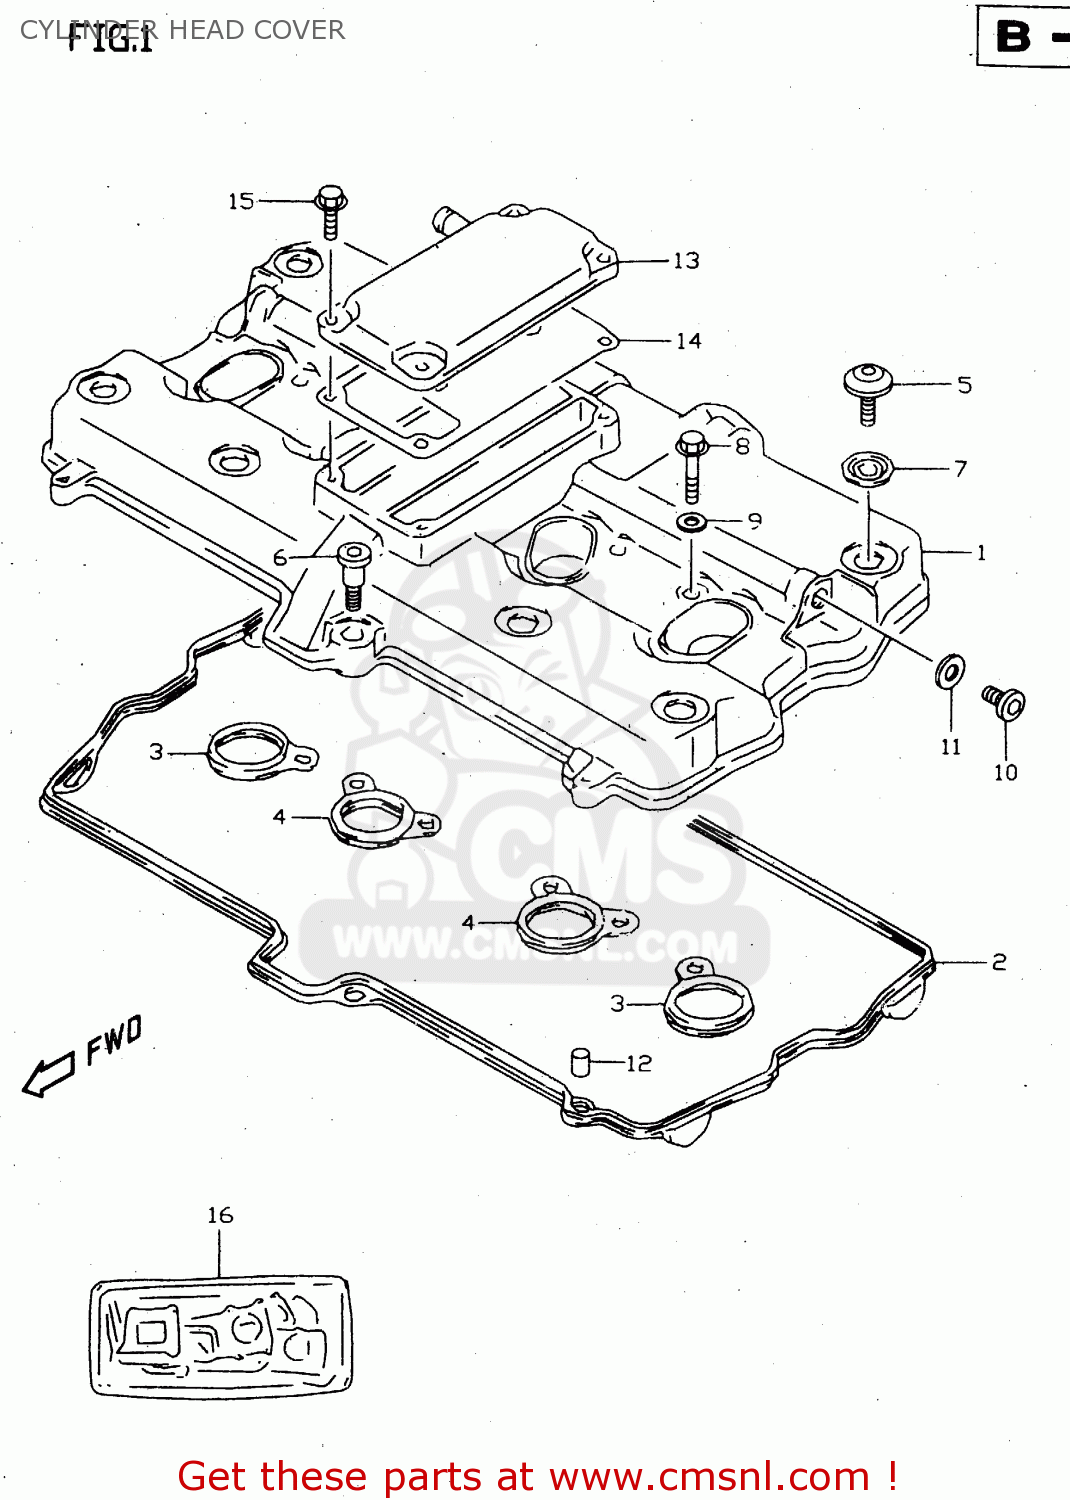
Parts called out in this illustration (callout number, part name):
1	COVER,CYLINDER HEAD
2	GASKET,CYLINDER HEAD COVER (NAS)
3	GASKET,HEAD COVER NO.2 (NAS)
4	GASKET,HEAD COVER NO.3 (NAS)
5	BOLT(7X17.5)
6	BOLT(7X31)
7	WASHER(10.6X25.5X2.3)
8	BOLT,UNION 8X35
9	GASKET 8.2X14X1 (NAS)
10	PLUG(L:12)
11	GASKET(12.1X16.2X3.7) (NAS)
12	PIN
13	COVER,BREATHER
14	GASKET,BREATHER COVER
15	BOLT
16	GASKET SET
